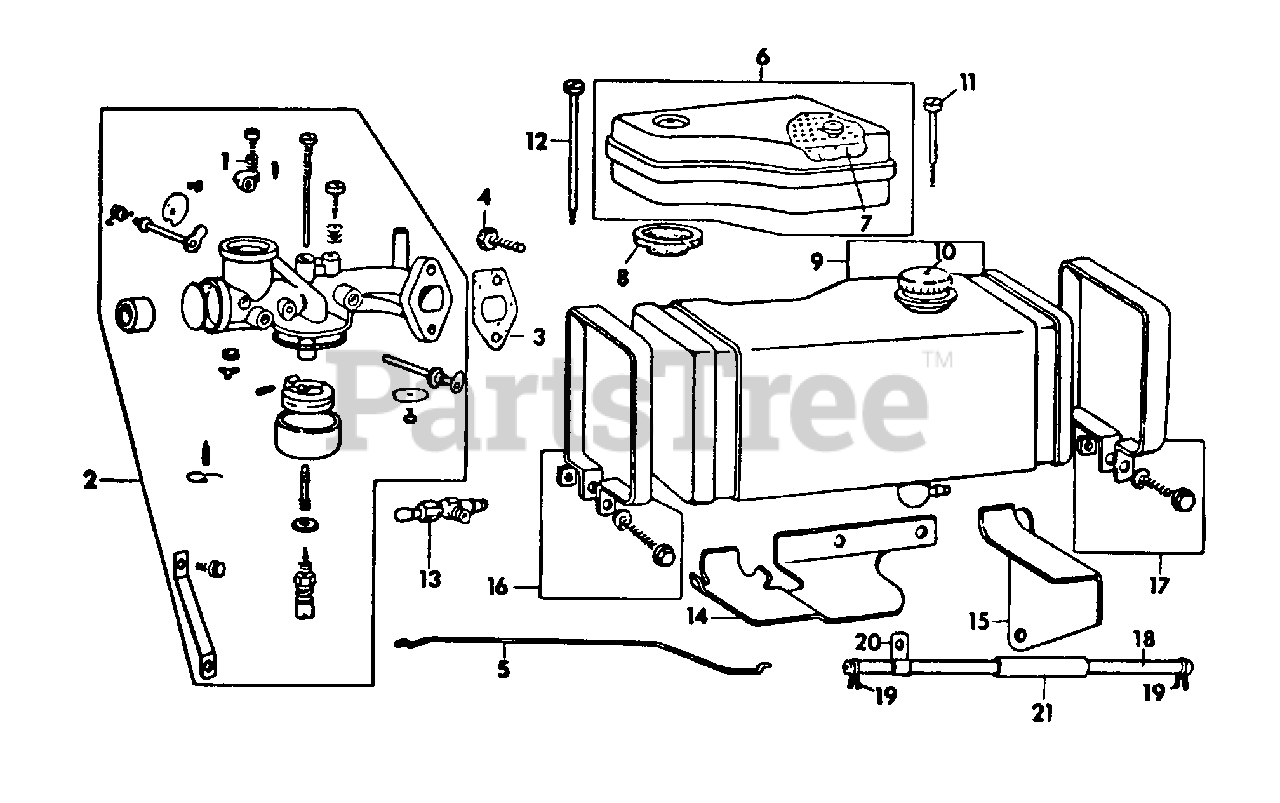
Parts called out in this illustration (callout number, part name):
1	SPRING, THROTTLE ADJUSTING
2	CARBURETOR ASSY
3	GASKET, CARBURETOR
4	SCREW, CARBURETOR MOUNTING
6	CLEANER ASSY, AIR
7	ELEMENT
8	GASKET, AIR CLEANER
9	TANK W/CAP, FUEL
10	CAP, FUEL TANK FILLER
11	SCREW, AIR CLEANER
12	SCREW, AIR CLEANER
13	CONNECTOR & FUEL SHUT-OFF
14	BRACKET, FUEL TANK FRONT
15	BRACKET, FUEL TANK REAR
16	STRAP, FUEL TANK FRONT
17	STRAP FUEL TANK REAR
18	HOSE, FUEL LINE
19	CLAMP, FUEL LINE HOSE
20	CLAMP, FUEL LINE HOSE
21	BUSHING, HEAT DEFLECTOR
